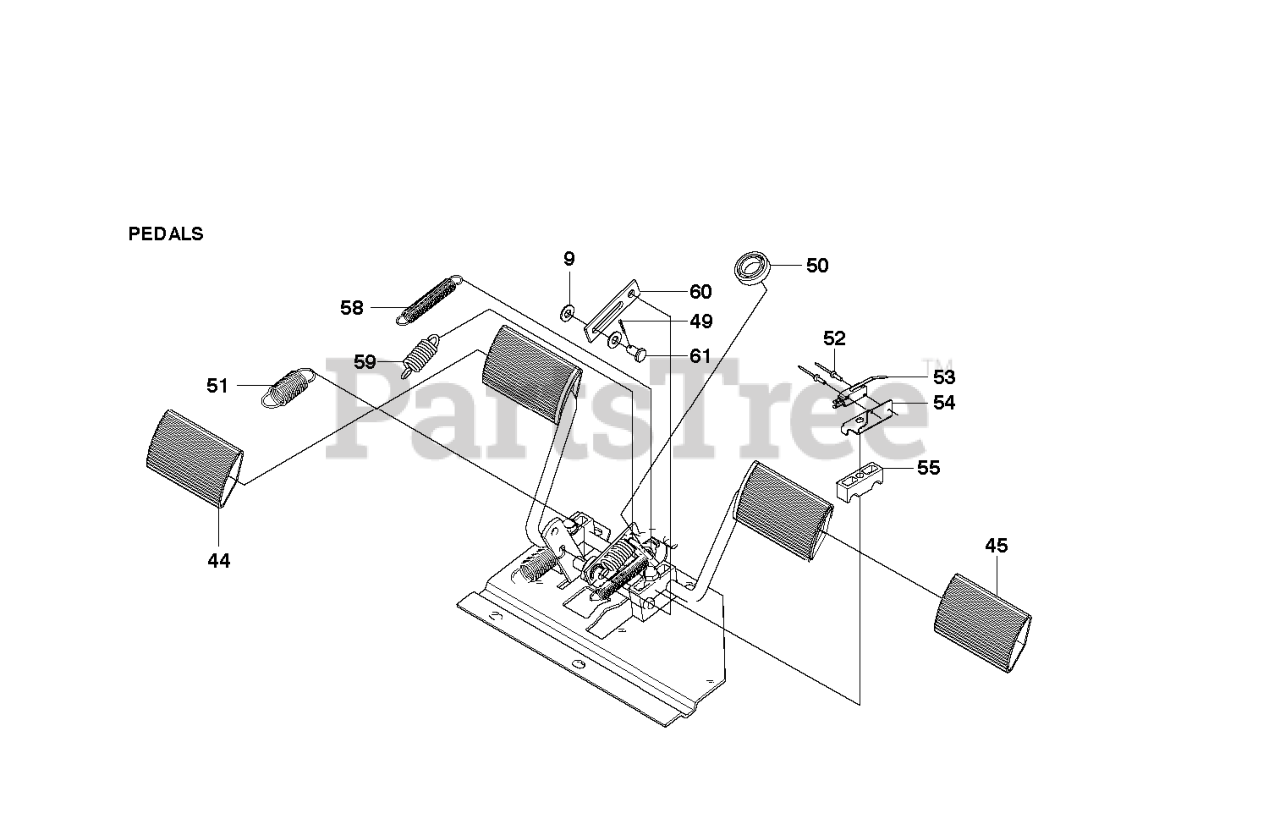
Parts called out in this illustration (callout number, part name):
9	WASHER BRB 8.4X17
44	PEDAL RUBBER, SF
45	PEDAL RUBBER
49	Cotter Pin
50	BALL BEARING 6002-2RS1
53	MICRO SWITCH
55	PEDAL SHAFT CLAMP
61	Clevis Pin
